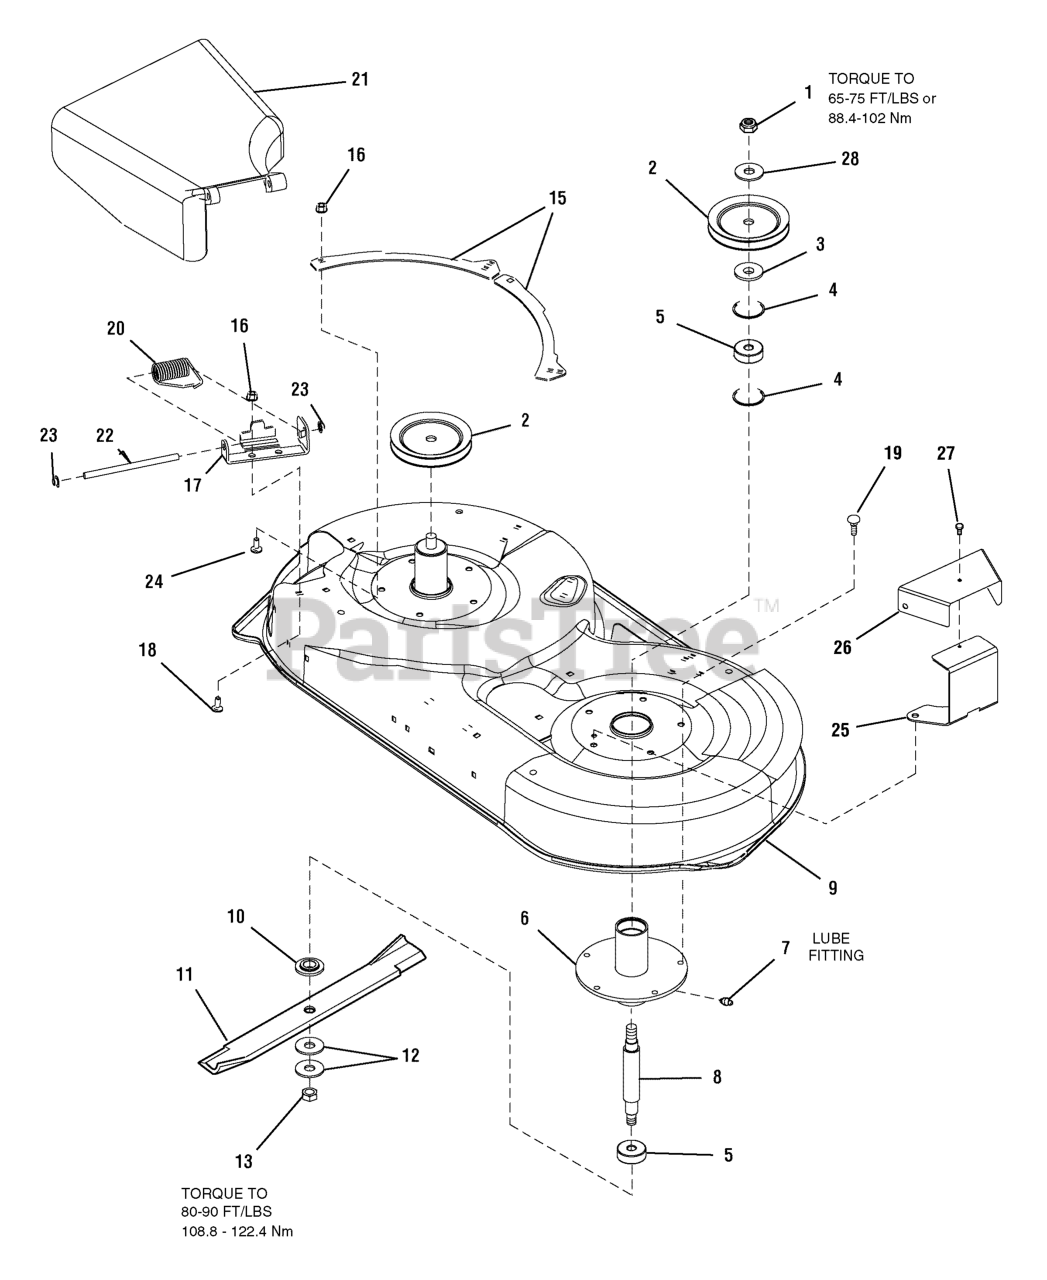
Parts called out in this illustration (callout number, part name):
1	NUT, Hex Lock, ESNA Light, 5/8-18
2	PULLEY, Drive, 5-1/2
3	SPACER, Pulley
4	RING, Retaining, 1-3/4
5	BEARING, Spindle
6	TUBE & PLATE ASSEMBLY, Spindle
7	LUBE, Fitting, 1/4
8	SHAFT, Spindle
9	HOUSING, 42"
10	WASHER, Spindle Blade, Powdered Metal
11	BLADE, Mower 42"
12	WASHER, Belleville
13	NUT, Hex, 9/16
15	PLATE, Rear
16	NUT, Hex Flange, 5/16-18 ESNA
17	BRACKET, Hinge
18	CARRIAGE BOLT, 5/16-18 x 3/4, G5
19	SCREW, Hex Washer Head Taptite, 3/8-16 x 3/4
20	SPRING, Torsion
21	DEFLECTOR ASSEMBLY
22	ROD, Deflector
23	NUT, Pushpal
24	CAPSCREW, Hex Head, 5/16-18 x 1 1/4
25	BRACKET, Pulley Cover
26	COVER, Pulley
27	SCREW, Hex Washer Head Taptite, 1/4-20 x 1/2
28	WASHER, Belleville
